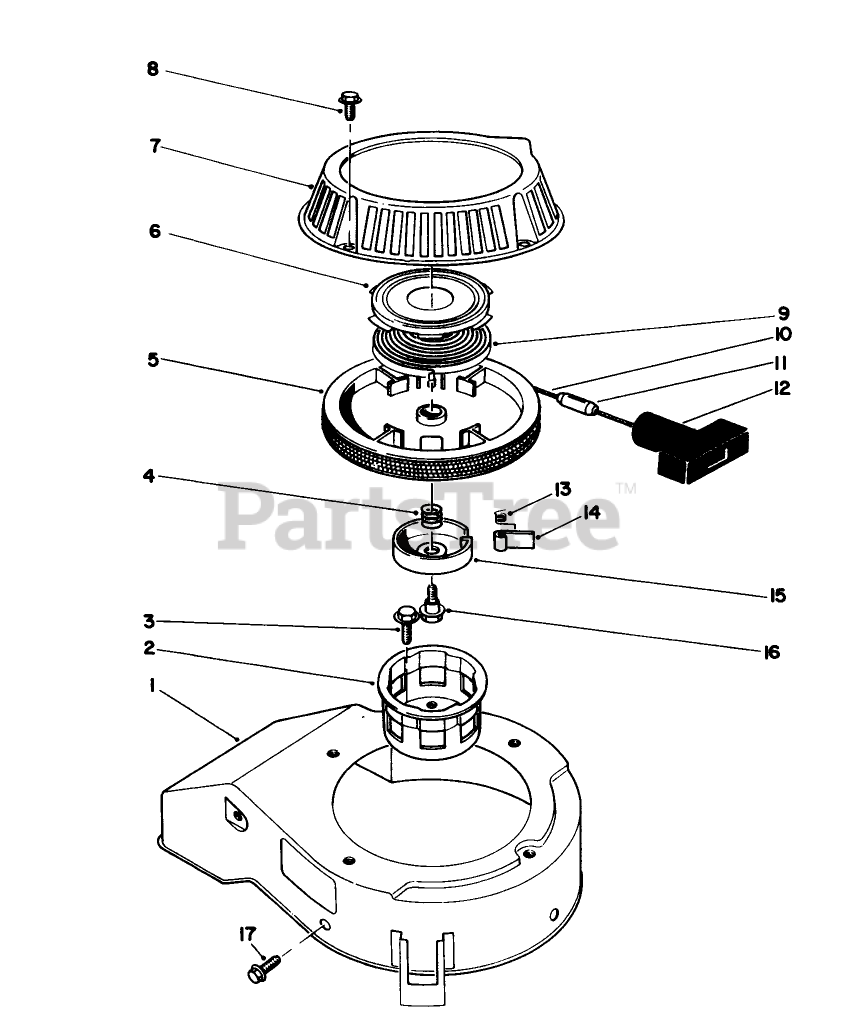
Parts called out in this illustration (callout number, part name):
2	CUP - STARTER
4	SPRING
8	SCREW-HHF
12	HANDLE-RECOIL
13	SPRING
15	RETAINER
